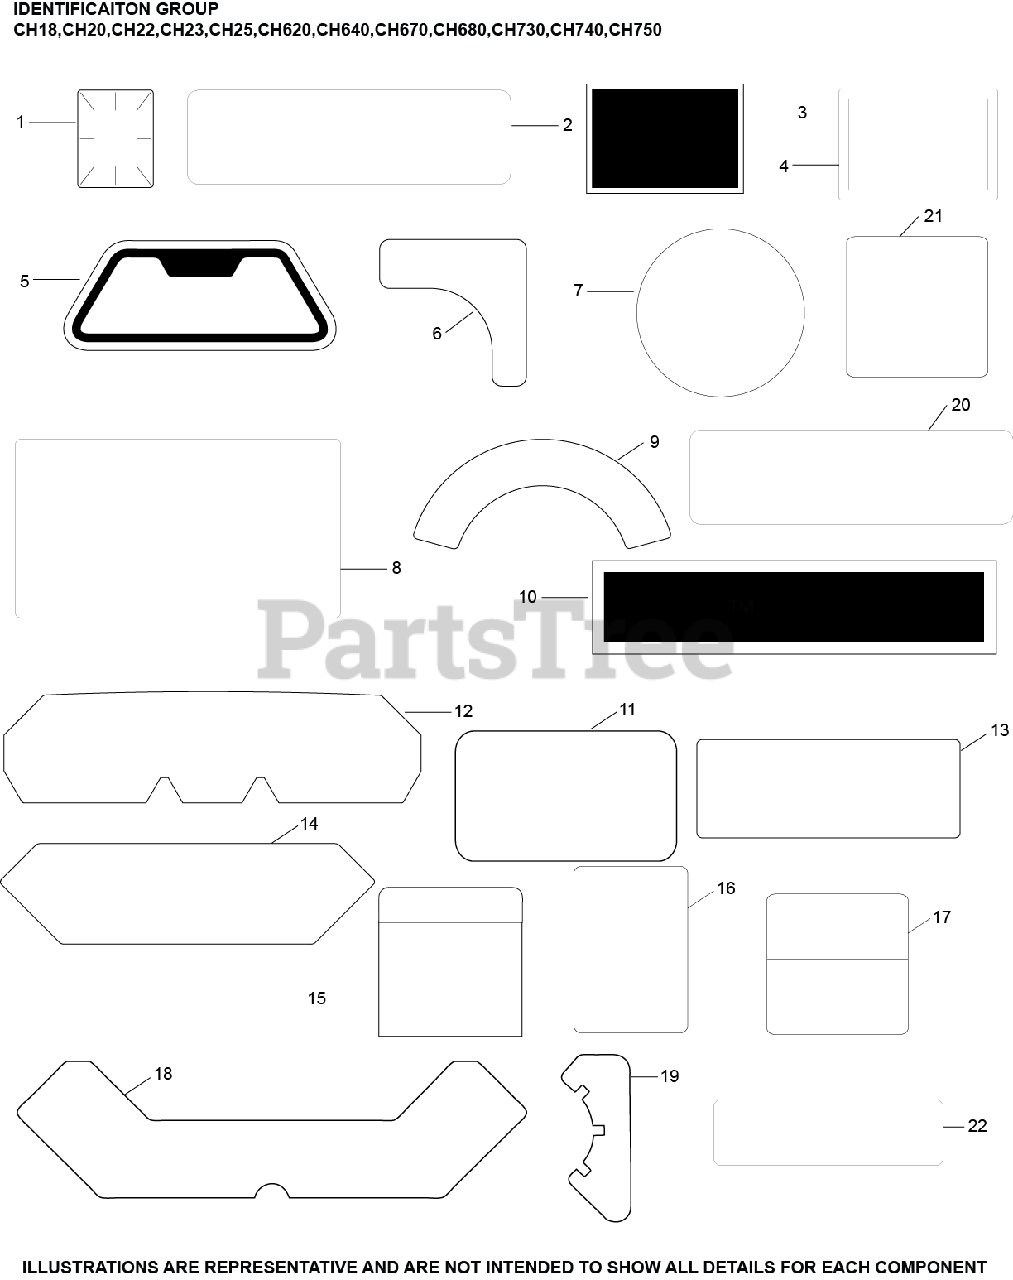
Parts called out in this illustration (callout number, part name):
1	LABEL, CLEAR LAMINATION - USE 25 113 79-S
2	DECAL, 18 HP
5	DECAL, OIL SENTRY - (#DSC)
6	DECAL, KEY SWITCH
10	DECAL, STOPPING INSTRUCTION
20	DECAL LPAC, 19 HP/674cc/CV-CH620
